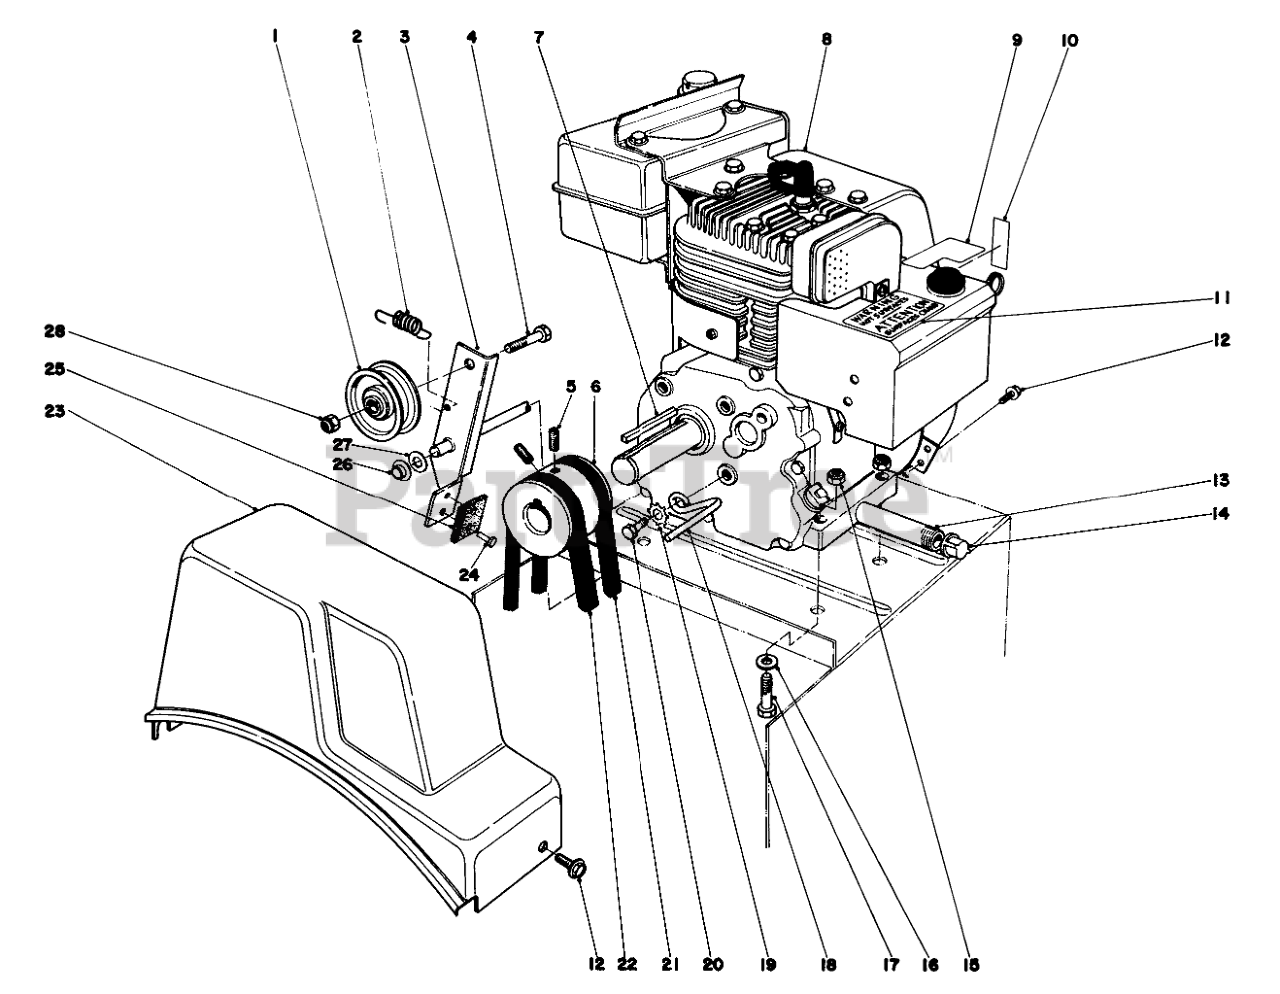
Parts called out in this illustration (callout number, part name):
1	PULLEY-IDLER
2	EXTENSION SPRING
3	Auger Clutch (Incl. Ref. #24 & #25)
4	SCREW-HH
5	Screw-Set
6	ENGINE PULLEY
8	Engine
9	CHOKE & PRIMER DECAL
10	DECAL THROTTLE
11	Decal Hot Surface Warning
12	SCREW
13	PIPE NIPPLE
14	CAP-PIPE
15	NUT-LOCK, NI
16	WASHER-FLAT
17	SCREW-HH
18	RETAINER-BELT
19	WASHER-LOCK
20	SCREW-HH
21	V BELT-3L, TRACTION
22	V-BELT (29.50 INCH)
23	COVER-BELT
24	.185 DIA X .375 RT +
25	BRAKE PAD
26	RETAINER-PUSH ON
27	WASHER-FLAT
28	NUT-LOCK, NI
